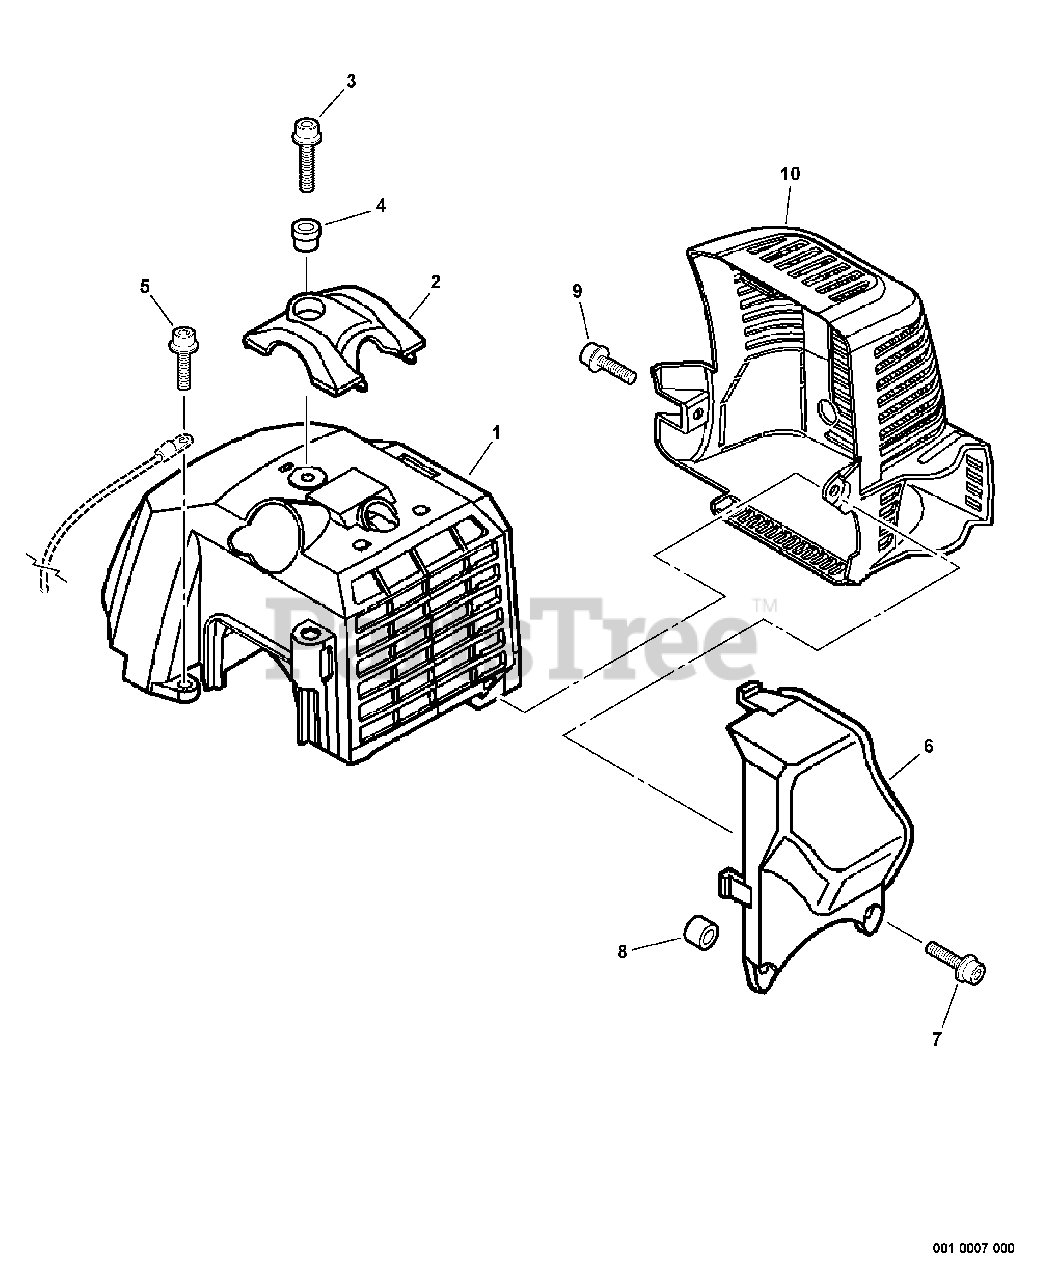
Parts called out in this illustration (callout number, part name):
1	COVER, ENGINE
2	GUARD, TOP
3	BOLT 5×20
4	COLLAR 5
5	BOLT 5×12
6	DEFLECTOR, EXHAUST
7	BOLT 5×25
9	BOLT 5×12
10	COVER, EXHAUST
